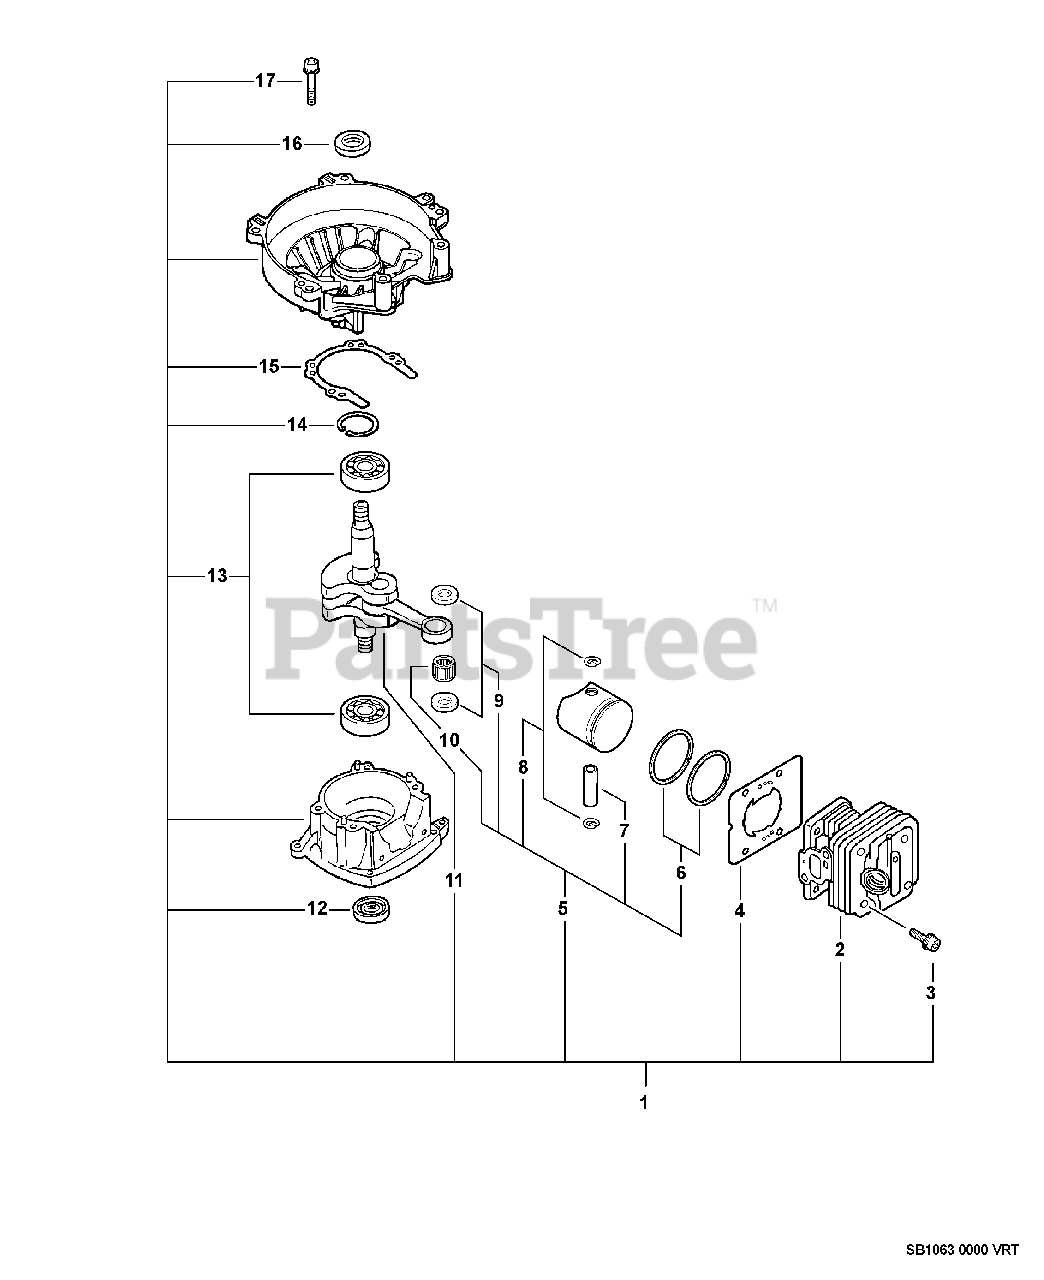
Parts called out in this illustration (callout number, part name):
1	SHORT BLOCK
2	CYLINDER
3	BOLT 5×22
4	GASKET, CYLINDER
5	PISTON KIT
6	RING, PISTON
7	PIN, PISTON 8
8	RING, SNAP
9	WASHER, THRUST
10	BEARING, NEEDLE 8
11	CRANKSHAFT ASSY
12	SEAL, OIL 12
13	BEARING, BALL 6001
14	RING, SNAP 28
15	GASKET, CRANKCASE
16	SEAL, OIL 12
17	BOLT 5×25
